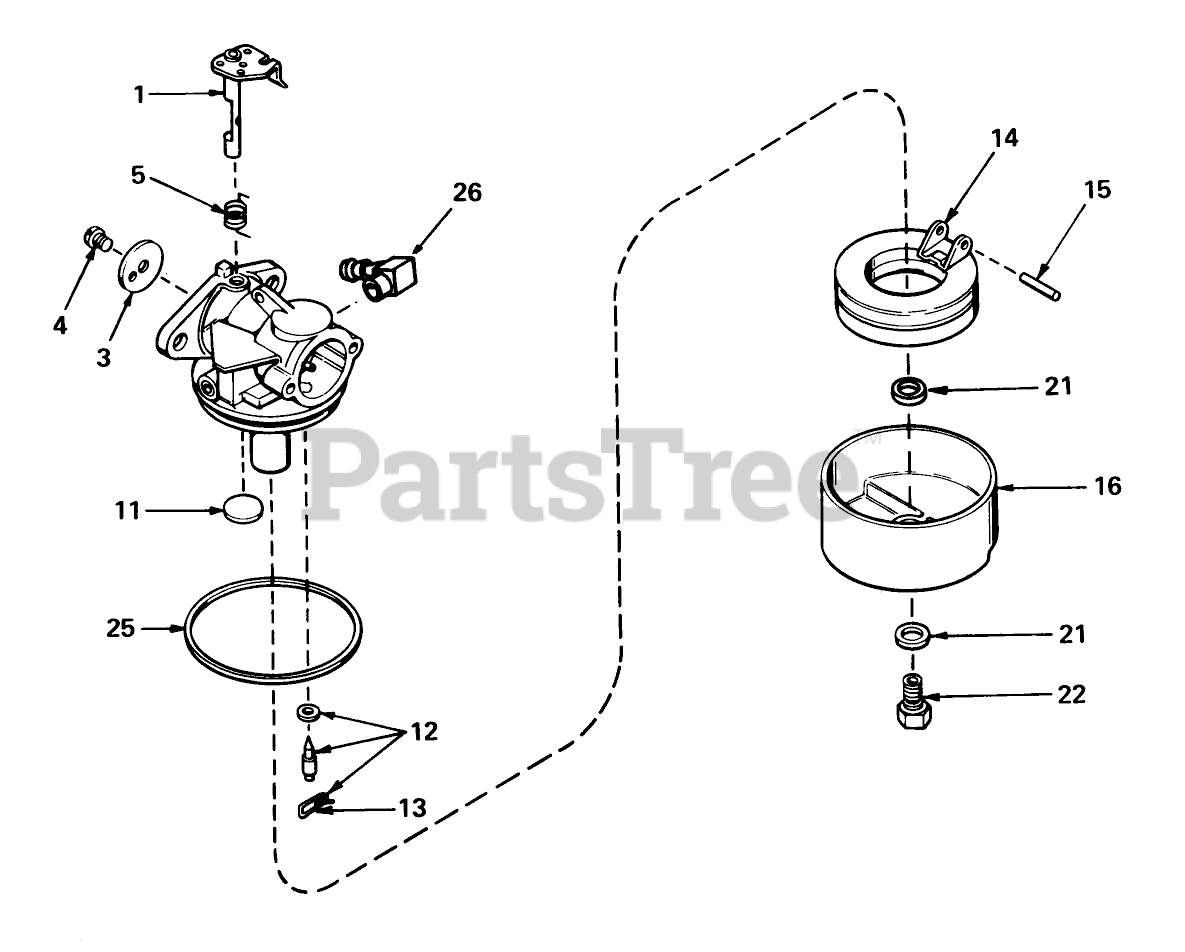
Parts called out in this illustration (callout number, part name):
1	Throttle Shaft and Lever ASM
3	Throttle-Shutter
4	Screw-Shutter
5	Spring, Return
11	Plug-Welch, Atmospheric Vent
12	Inlet Needle, Seat Clip Assy. (Incl. No. 13)
13	Clip-Spring
14	Float,Carburetor
15	Shaft-Float
16	Bowl Float
21	Gasket-Bowl
22	Nut, Float Bowl
25	O Ring-Bowl, Float
26	Fitting-Fuel
